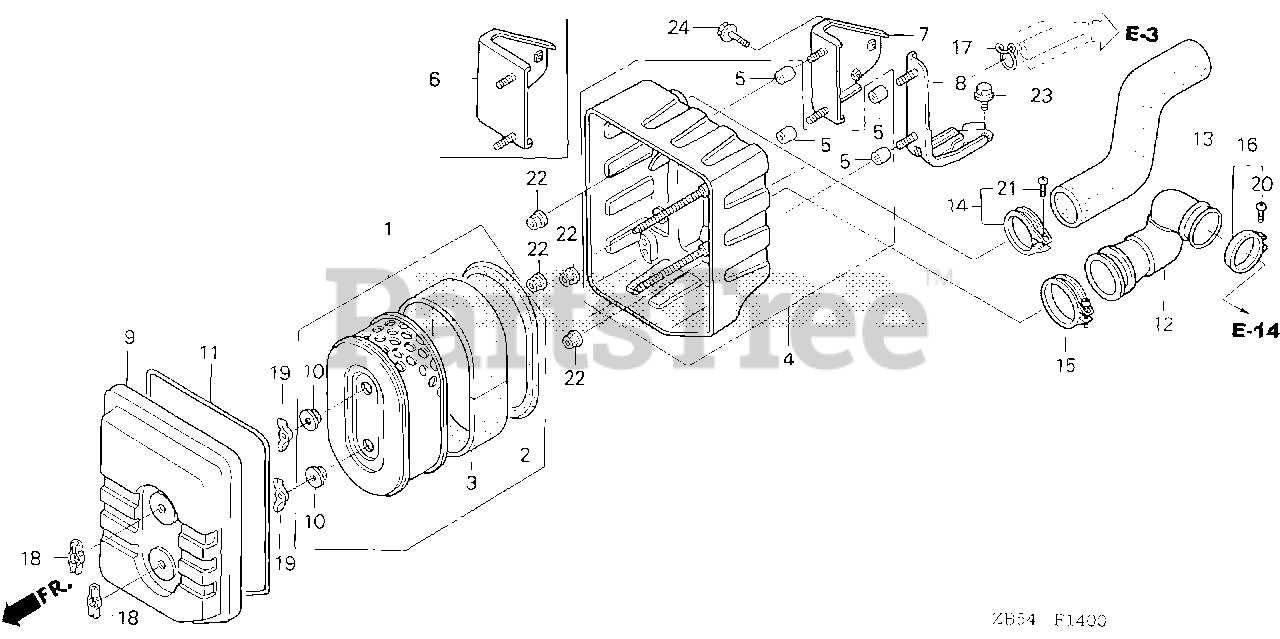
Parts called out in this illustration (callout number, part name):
1	ELEMENT, AIR CLEANER
2	GASKET, AIR CLEANER
3	FILTER (OUTER)
4	HOUSING, AIR CLEANER
5	COLLAR, CONNECTING TUBE SETTING
7	STAY C, AIR CLEANER (4K.V.A)
8	STAY B, AIR CLEANER
9	COVER, AIR CLEANER
10	GROMMET, AIR CLEANER
11	SEAL, AIR CLEANER COVER
12	TUBE, AIR CLEANER CONNECTING
13	TUBE, AIR CLEANER IN.
14	BAND, AIR CLEANER CONNECTING TUBE
15	BAND, AIR CLEANER CONNECTING TUBE
16	BAND, CONNECTING TUBE
17	CLIP, BREATHER TUBE
18	WINGNUT (6MM) (BLACK)
19	NUT, TOOL BOX SETTING
20	SCREW, PAN (4X16)
21	SCREW, PAN (4X20)
22	NUT, FLANGE (6MM)
23	BOLT, FLANGE (6X12)
24	BOLT, FLANGE (6X18)
